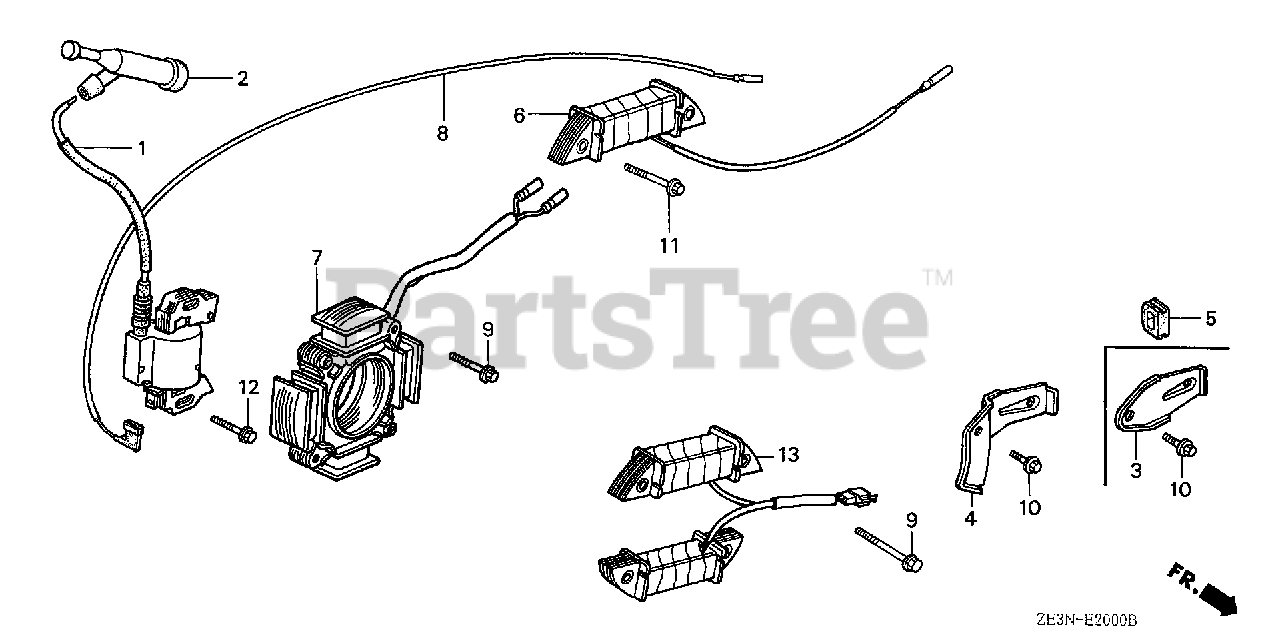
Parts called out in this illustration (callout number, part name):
1	COIL ASSY., IGNITION
2	CAP ASSY., NOISE SUPPRESSOR
4	CLAMP, WIRE
5	GROMMET, WIRE
6	COIL ASSY., CHARGE
8	WIRE, STOP SWITCH (470MM)
10	BOLT, FLANGE (6X12) (CT200)
11	BOLT, FLANGE (6X35)
12	BOLT, FLANGE (6X28)
